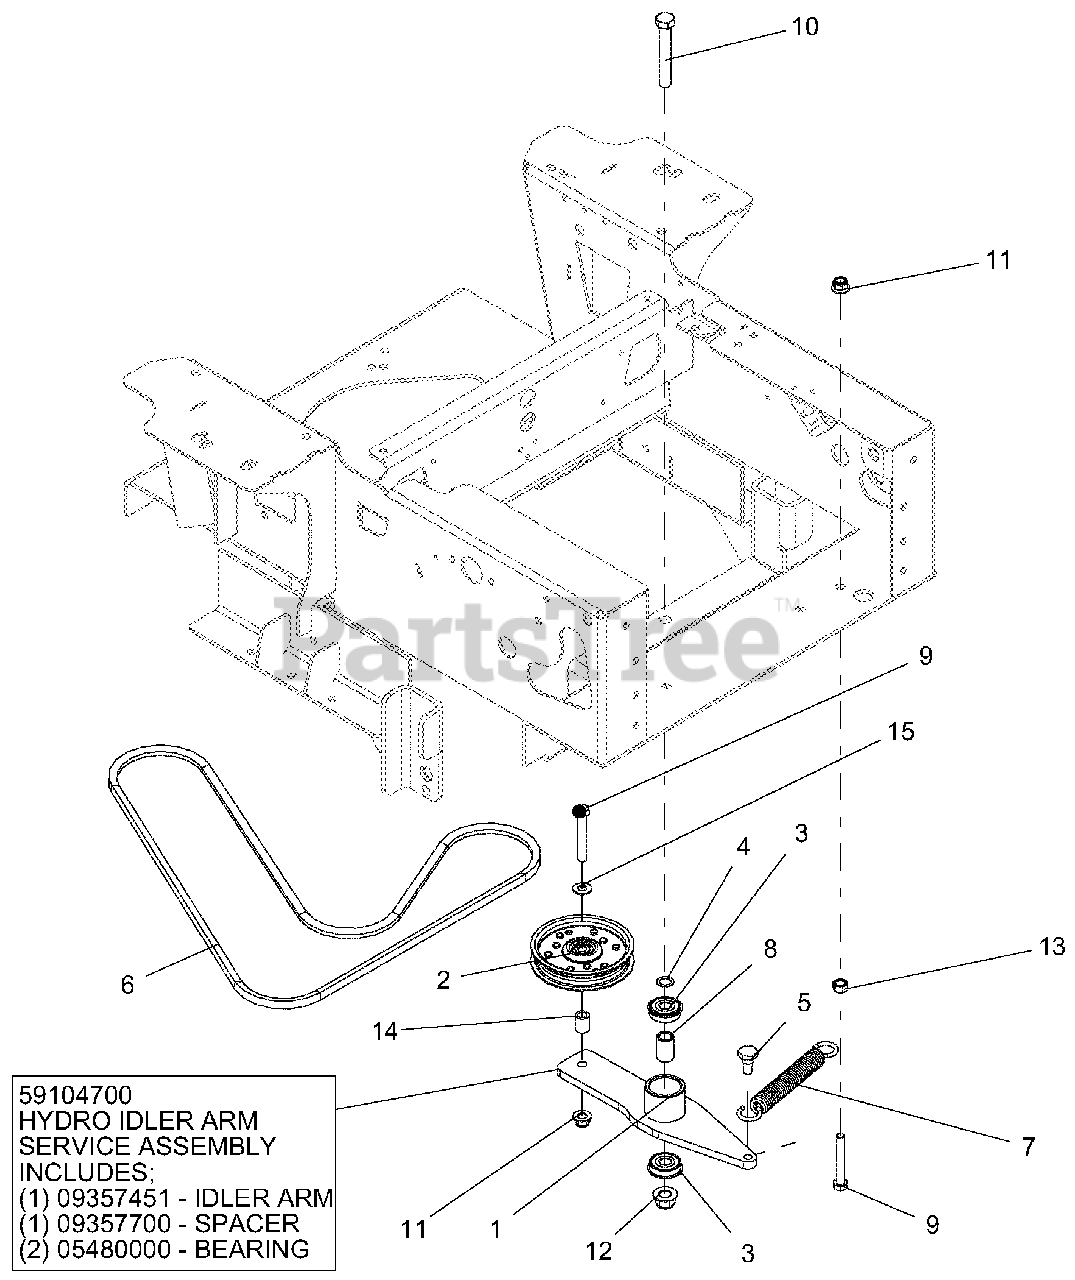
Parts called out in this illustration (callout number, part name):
1	HYDRO IDLER ARM ASM.
1	WLDMT, HYDRO DRIVE IDLER ARM-BLACK
1	IDLER ARM
2	ASM, IDLER 4"
3	BRG, BALL .501 X 1.38 X .438 SEALED
4	WASHER-FLAT-STL, .500 X .750 X .020
5	BLT, SHLDR EP .38-16X.30 HEX YZ
6	BELT, V-A-COGGED
7	SPRG, EXTENSION
8	SPACER, .510 X .750 X 1.148
9	BLT-HEX .38-16X2.50 GR5 YWZC
10	BLT-HEX .50-13X3.25 GR5 YWZC
11	NUT-LK-NYL-FLG .38-16 YWZC
12	NUT-LK-NYL-FLG .50-13 YWZC
13	NUT-HEX .38-16 YWZC
14	BSHG-SLV .407X.625X.750
15	WSHR-FL-STL.406X.812X.065 YWZ
